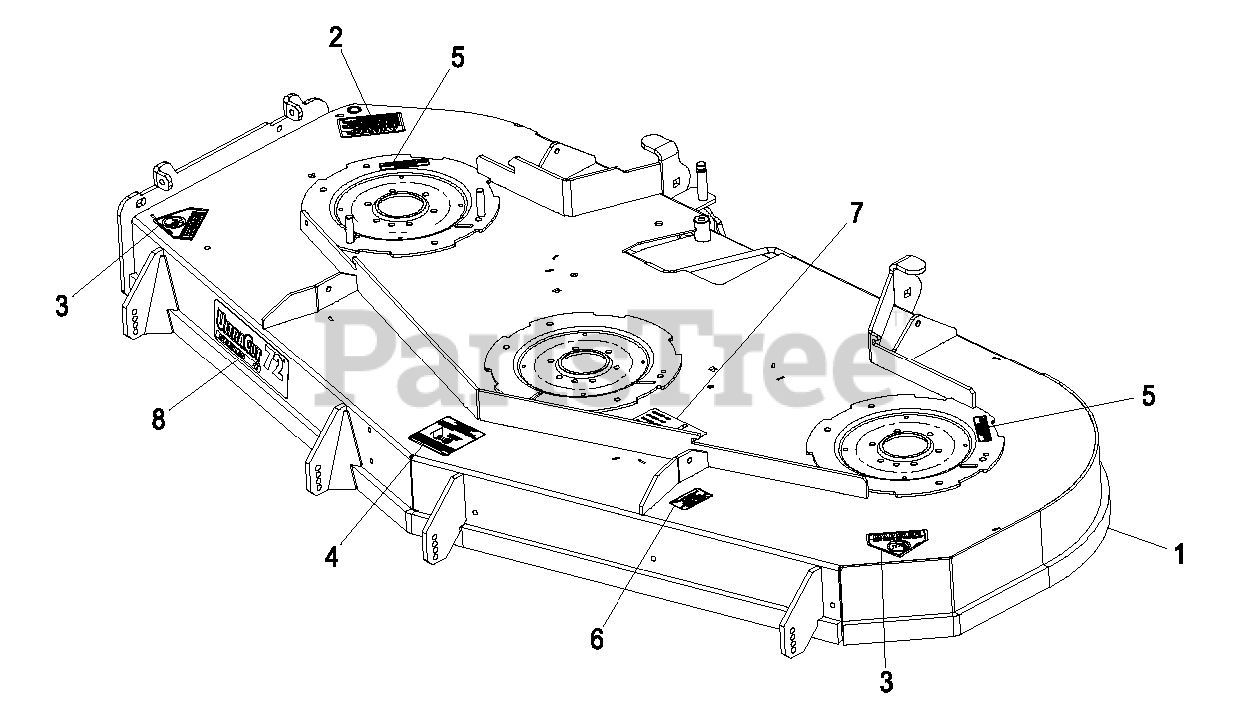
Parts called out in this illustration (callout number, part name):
2	DECAL-WARNING, DISCHARGE
3	DECAL-DANGER
4	DECAL,ANTISCALP
5	DECAL-COVER, MISSING
6	DECAL,BOLT TORQUE
7	DECAL,BELT ROUTING
8	DECAL,ULTRACUT 72 SERIES
